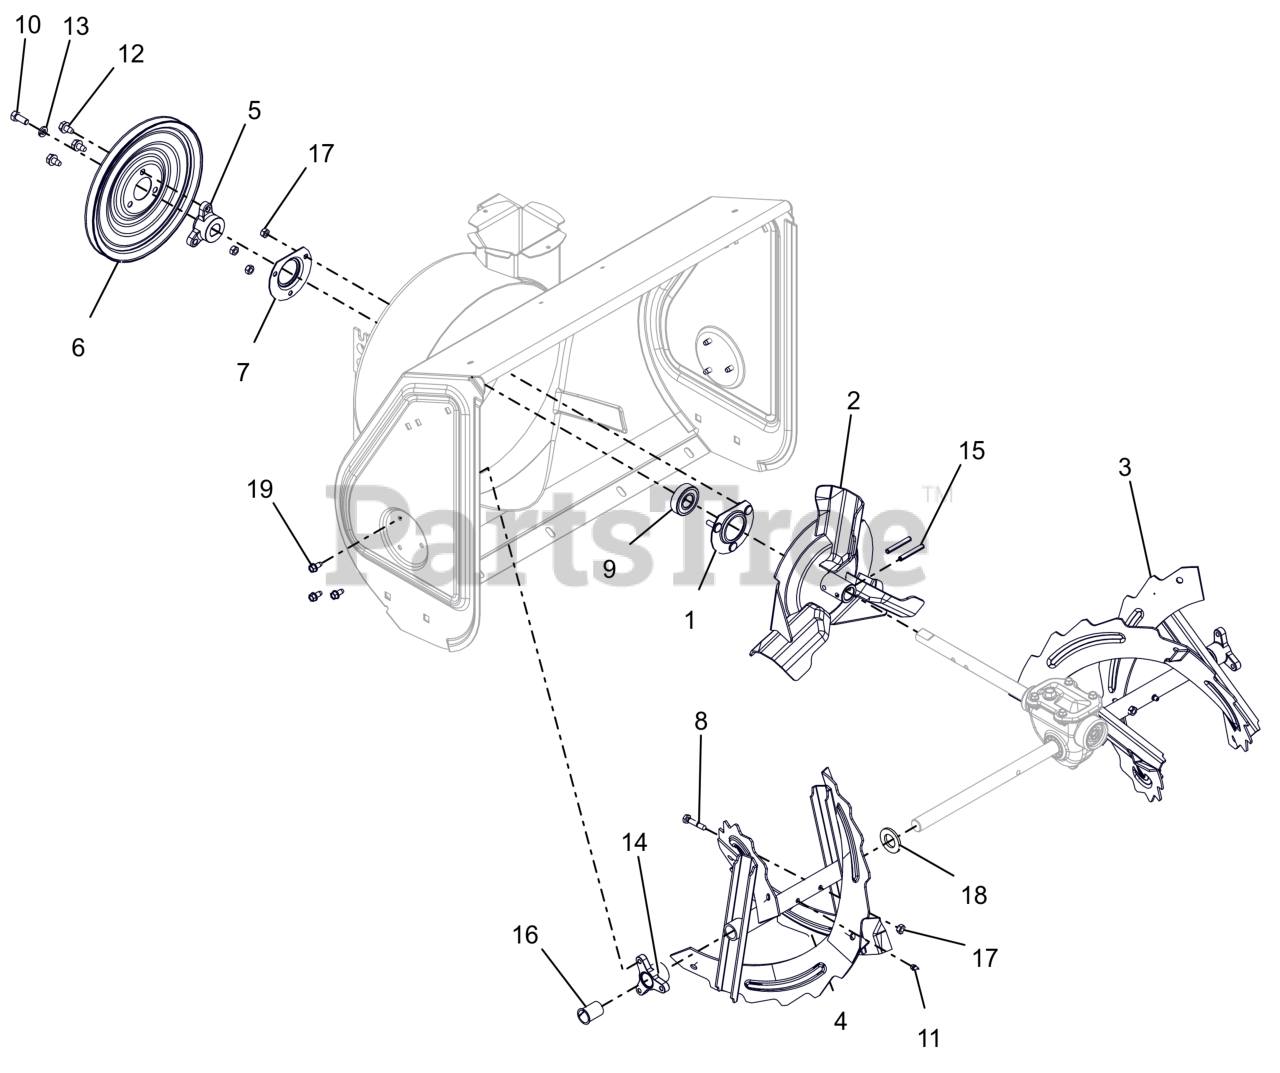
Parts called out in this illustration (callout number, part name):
1	BEARING FLANGE
2	IMPELLER, COMPACT 12" 3-BLADE
3	RAKE, 24" LH, BLK SERR W/ZERK
4	RAKE, 24" RH, BLK SERR W/ZERK
5	PULLEY HUB, BOLT-ON D-BORE .75
6	PULLEY,SPIN FORM SINGLE GROOVE
7	BEARING FLANGE
8	SHEAR BOLT
9	BRG-BALL .750X1.750X.50
10	BLT, HEX .31-24X.750 G5 ZCC
11	ZERK,FITTING .25X.125 DRIVE IN
12	SCR,TAP .312-18X.50 HWH TR ZCC
13	WSHR, LK-HVY .312X.097 ZCC
14	BUSHING, RAKE SHAFT .75"
15	PIN-ROLL .250X1.75
16	BSHG-FLG SPLIT NYLINER .75"ID
17	NUT,LK-CTR .25-20 GA ZCC
18	WSHR, FLT .812X1.469X.134 ZCC
19	SCR-TAP .25-20X.50 HWH ZCC
